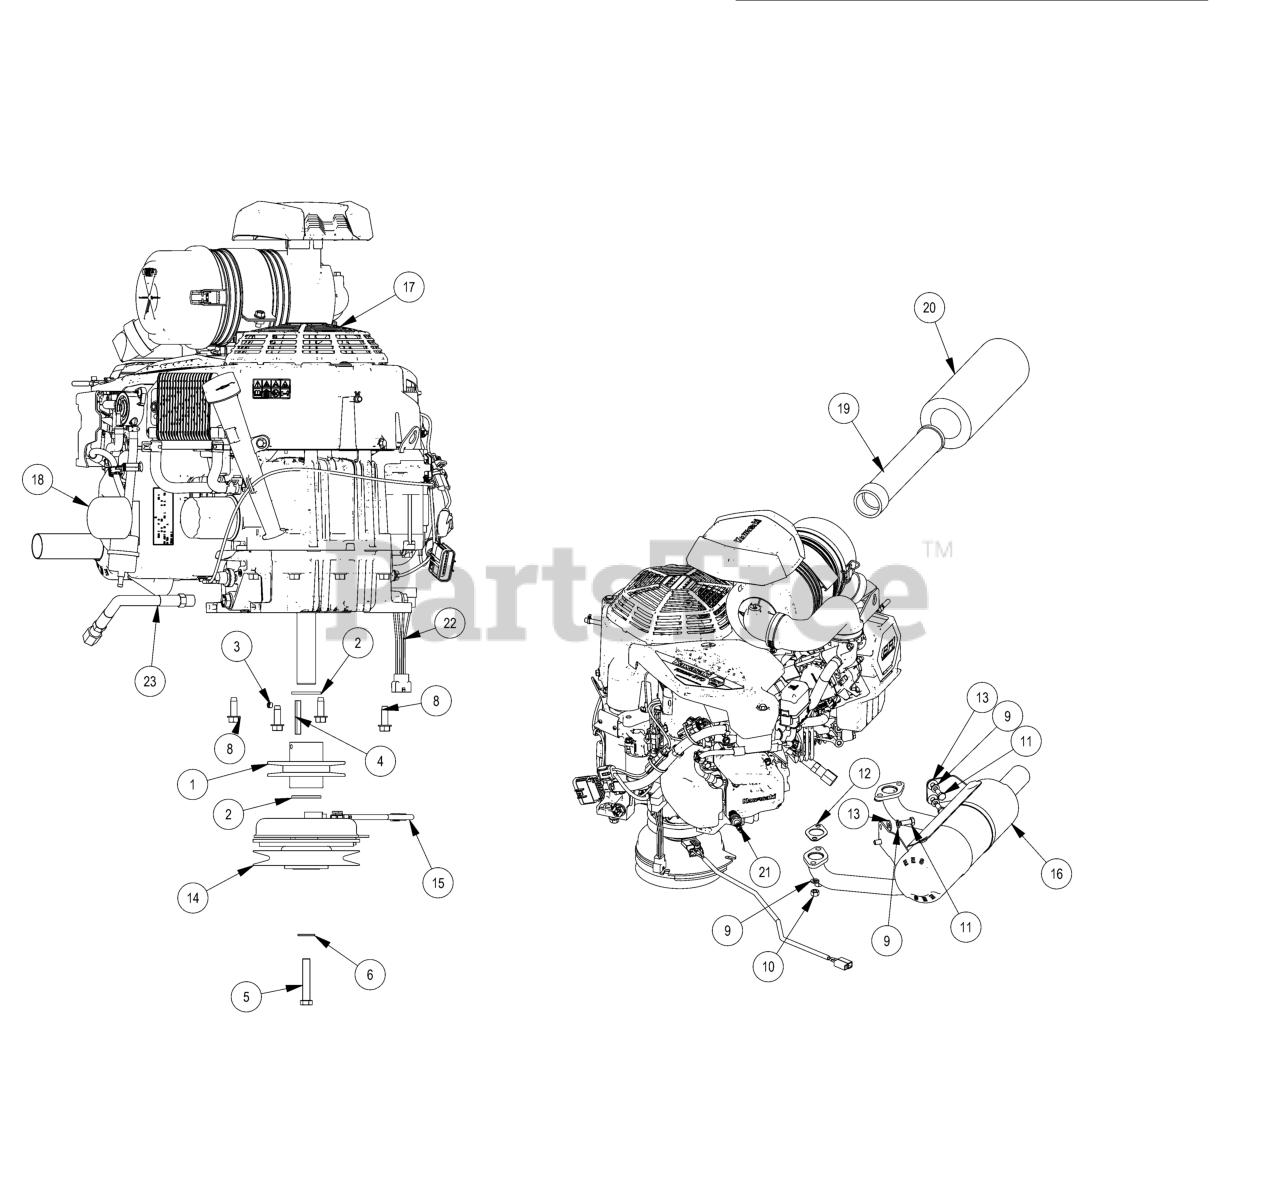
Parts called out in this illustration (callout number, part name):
1	4 3/4 Motor Pulley
2	1.140 ID X 1.750 OD X .132 THICK FLAT WASHER PLAIN
3	5/16-24 X 1/4 SOCKET SET SCREW (CUP PT) PLAIN
4	1/4 X 2 SQ MACHINERY KEY 1018 STL PLAIN
5	7/16-20 X 2-1/2 HEX CAP SCREW (GR.8) ZINC YELLOW
6	3/8 FLAT WASHER USS (1" OD) ZINC
8	3/8-16 X 1-1/8 HEX WASHER UNSLOT SERRATED (TRI-LOB) TRS ZINC YELLOW
9	5/16 SPLIT LOCKWASHER ZINC
10	M8-1.25 DIN 934 HEX NUT (CL.8) ZINC
11	M8-1.25 X 20MM DIN 933 HEX TAP BOLT (CL 8.8) ZINC
12	Exhaust Gasket
13	1/4 USS FLAT WASHER (3/4 OD) ZINC
14	Clutch Assembly
15	Clutch Pigtail
16	FXEVO Revolt Muffler
17	Kawasaki FX820V EVO
18	Oil Filter
19	Inner Air Filter
20	Outer Air Filter
21	Spark Plug
22	Harness Adaptor for Kawasaki EFI
23	Oil drain Hose
